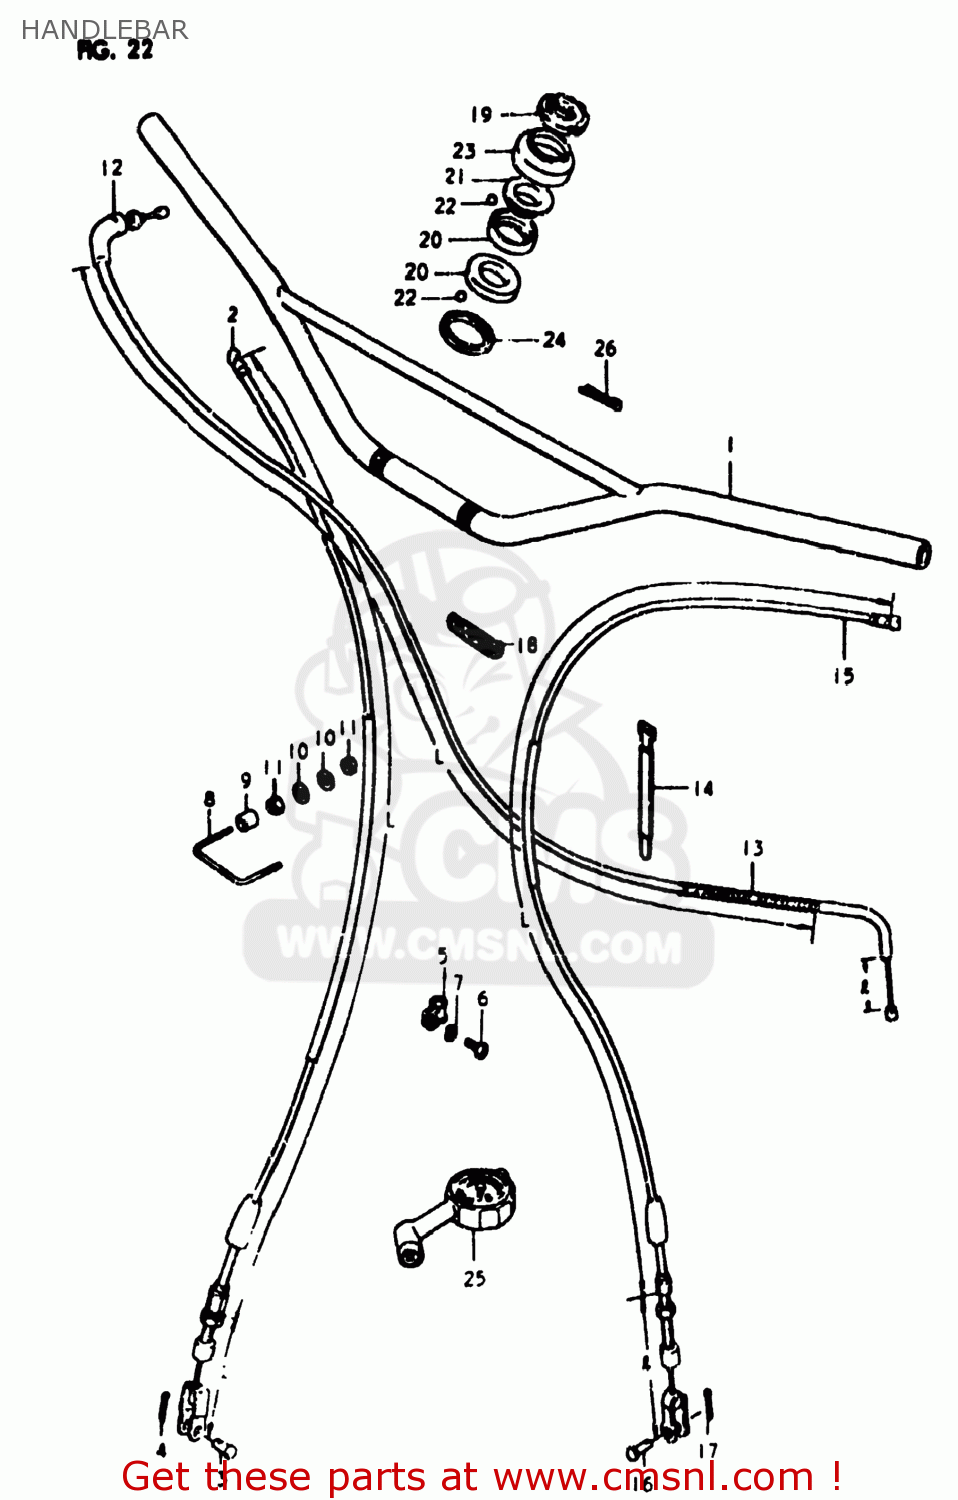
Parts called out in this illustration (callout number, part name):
1	HANDLEBAR
2	CABLE ASSEMBLY,FRONT BRAKE
3	PIN(L:17.5)
4	PIN
5	GUIDE,CABLE
6	SCREW
7	LOCK WASHER
8	CLAMP,CABLE
9	BUSHING
10	WASHER
11	NUT 3MM
12	CABLE ASSEMBLY,THROTTLE
13	PROTECTOR,CABLE
14	CLAMP
15	CABLE ASSY,CLUTCH
16	PIN(L:13)
17	PIN
18	CLAMP L:35
19	NUT,STEERING STEM
20	RACE,STEERING,INNER,UPPER
21	RACE,STEERING,OUTER,UPPER
22	BALL
23	SEAL,STEERING UPR DUST
24	DUST SEAL,STEERING HEAD
25	GAUGE ASSY,AIR PRESSURE
26	PIN 20X20
